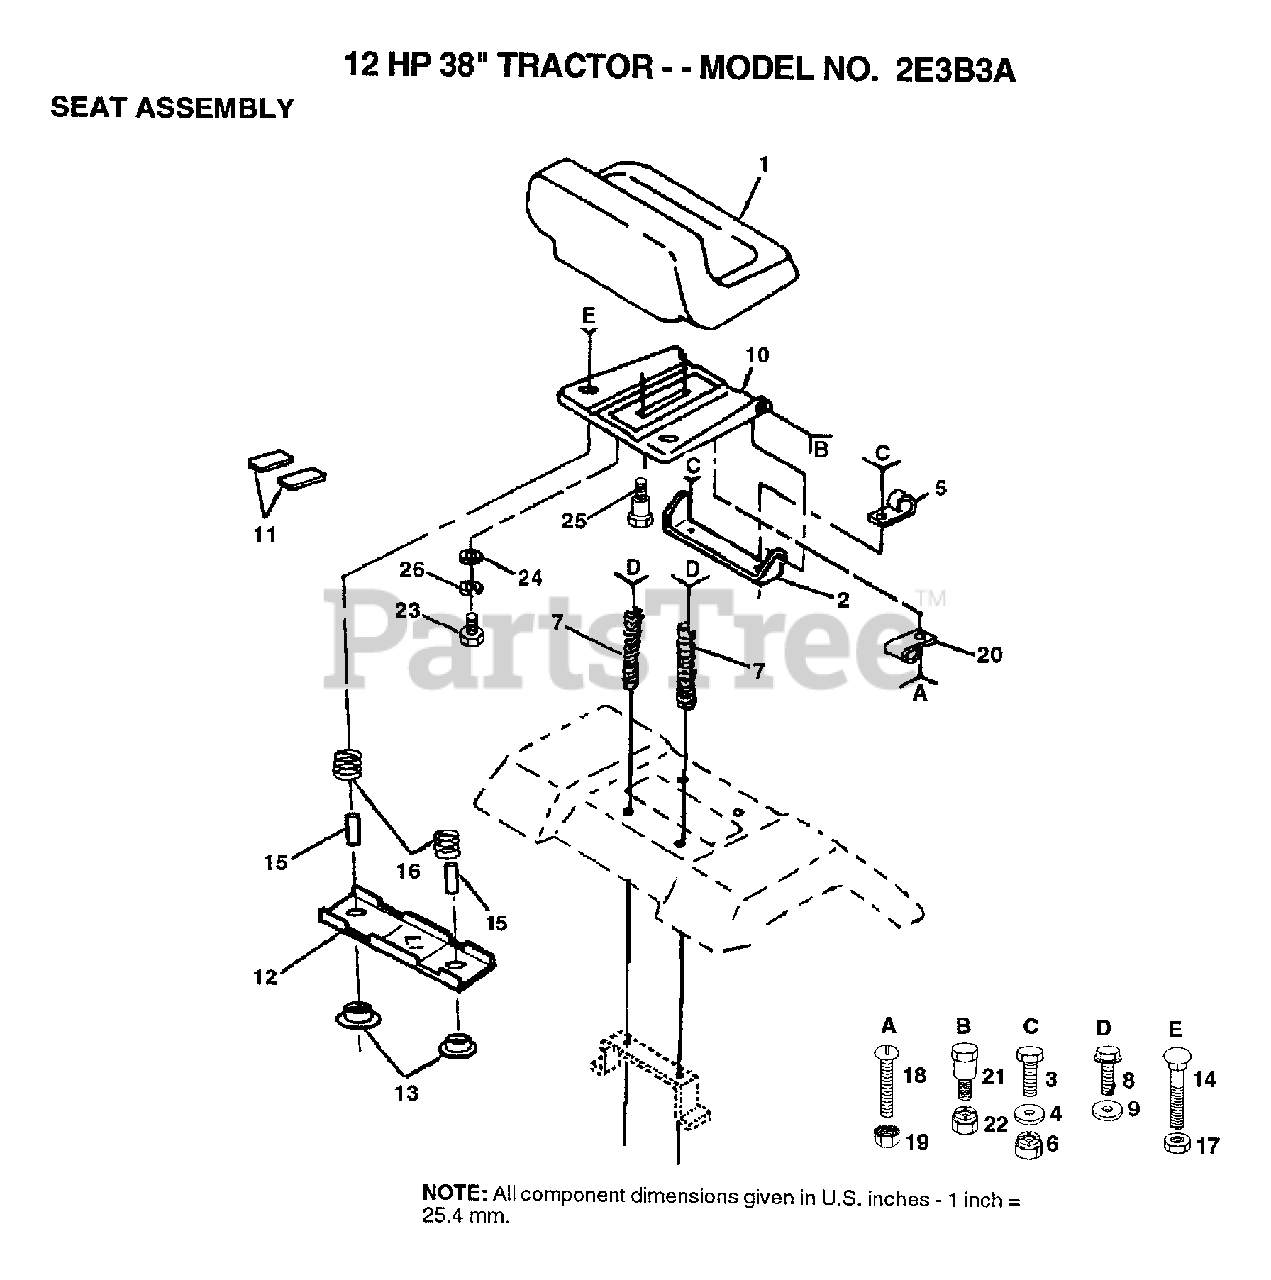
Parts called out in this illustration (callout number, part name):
4	WASHER
5	CLIP T
7	SPRING COMPRESSIO
8	SCREW GTV
9	WASHER
11	STRIP FORM
12	BRKT SWITCH
13	BUSHING
15	SPLIT SPACER
16	SPRING
19	"NUT,KEPS"
23	BOLT
24	WASHER
25	"BOLT,SHOULDER"
26	LOCKWASHER
